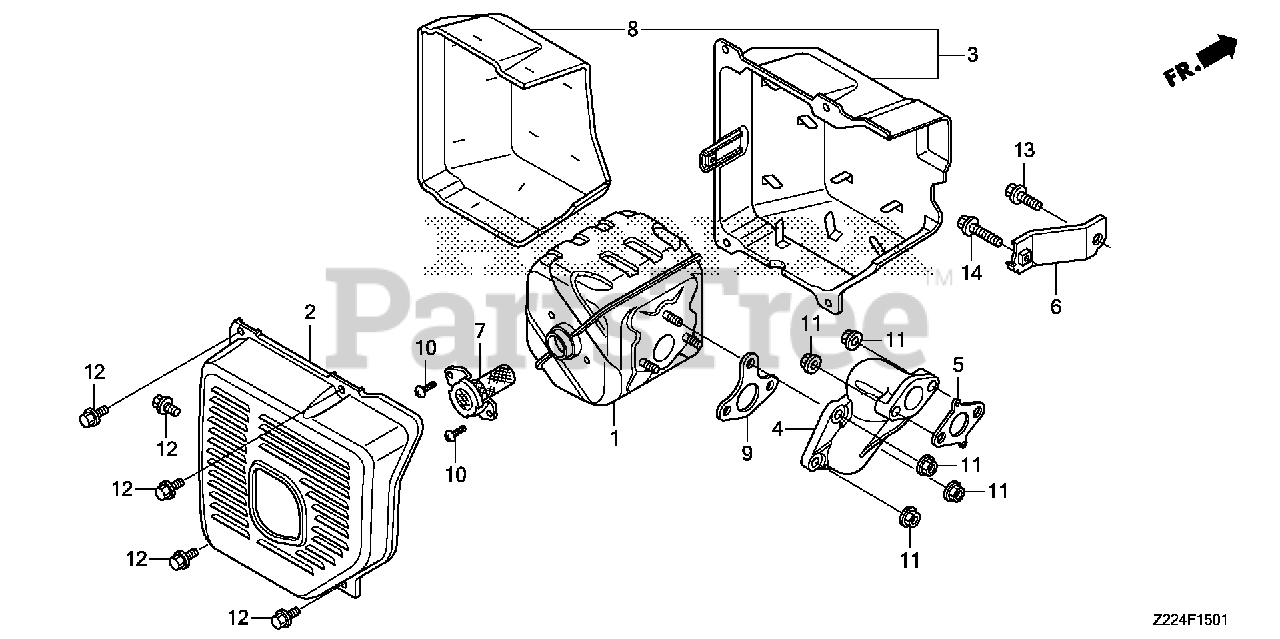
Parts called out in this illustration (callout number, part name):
1	MUFFLER
2	PROTECTOR, MUFFLER (OUTER) *NH105* (MAT BLACK)
3	PROTECTOR ASSY., MUFFLER (INNER) *NH105* (MAT BLACK)
4	PIPE, EX.
5	GASKET, EX. PIPE
6	STAY, MUFFLER
7	ARRESTER, SPARK
8	INSULATOR, MUFFLER PROTECTOR
9	GASKET, MUFFLER (NIPPON LEAKLESS)
10	SCREW, TAPPING (5X8)
11	NUT, FLANGE (8MM)
12	BOLT, FLANGE (6X10)
13	BOLT, FLANGE (8X16) Use from Engine SN 1000016.
14	BOLT, FLANGE (8X22) Use from Engine SN 1609607.
